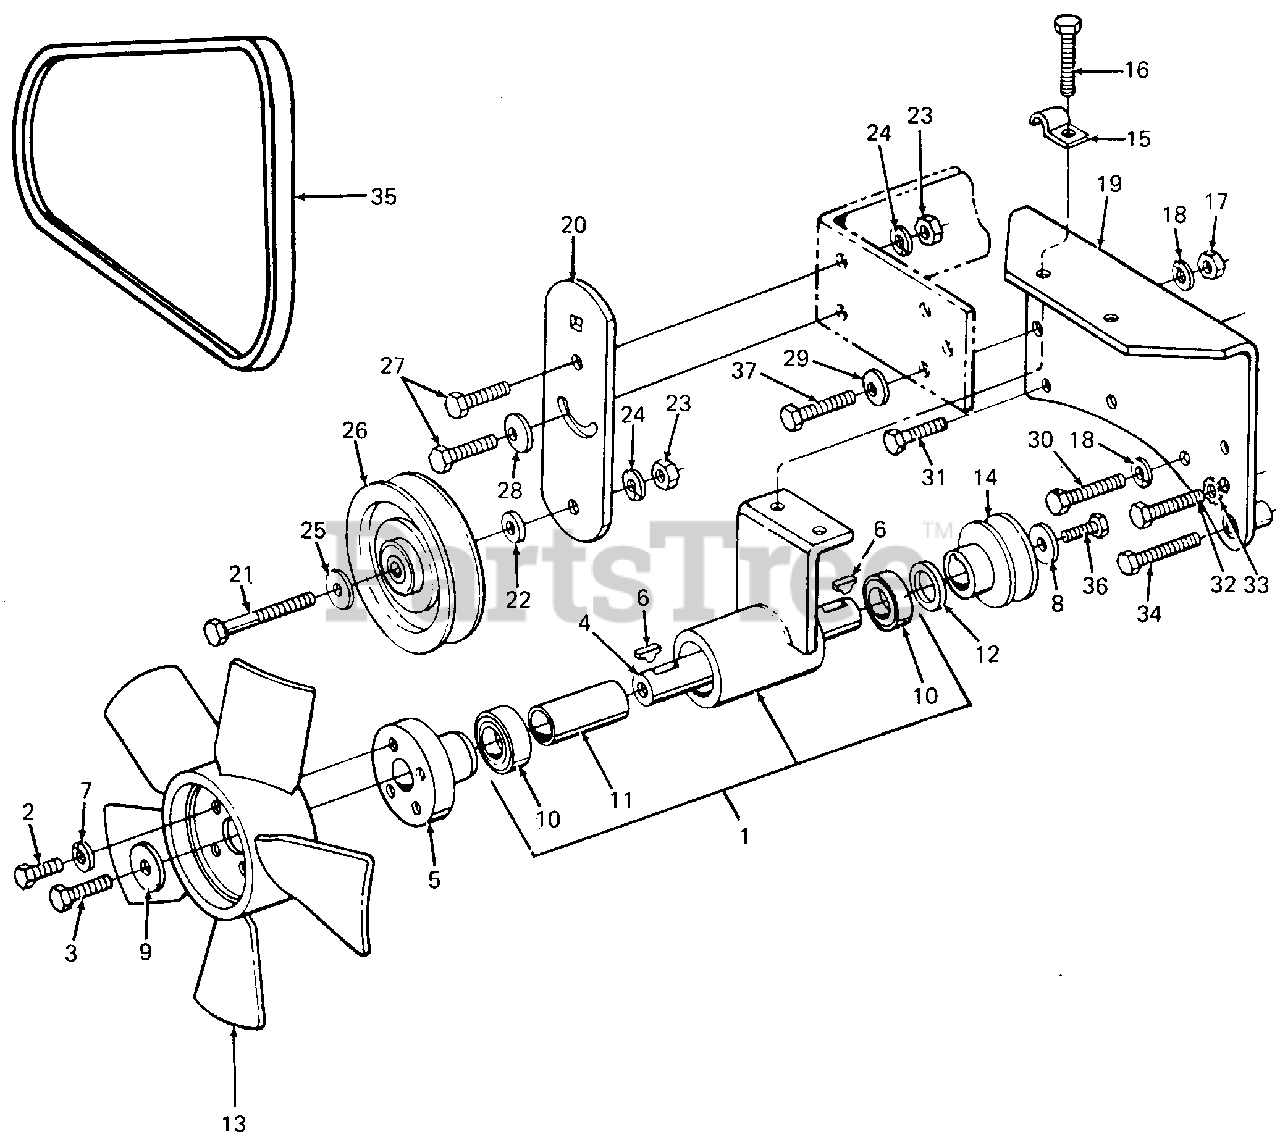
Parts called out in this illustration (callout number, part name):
1	Bracket Assy, Fan
2	Screw, Hex Cap, 1/4-20 X .62 Lg GR5
3	Screw, Hex Patch Lock, 5/16-18 X 1.12 Lg GR5
4	Shaft, Fan
6	Key, #61 HI-PRO, 3/16 X 5/8 Dia
7	Washer, Lock, 1/4
8	Washer, Flat, .344 X 1.12 X .125 Thk HDN
9	Washer, Flat, .344 X 1.0 X .063 Thk HDN
10	Bearing, Ball, .75 X 1.625 X .437
11	Spacer, .755 X 1.0 X 2.110 Lg
12	Spacer, .755 X .94 X .150 Lg
14	Pulley, Engine, 2.38 OD
15	Clip, Cable
16	Screw, Hex Patch Lock, 5/16-18 X .88 Lg GR5
17	Nut, Hex, 5/16-24 GR5
18	Washer, Lock, 5/16
19	Bracket, Fan Mounting
20	Bracket, Idler
21	Screw, Hex Cap, 3/8-16 X 1.75 Lg GR5
22	Spacer, .385 X .625 X .312 Lg
23	Nut, Hex Center Lock, 3/8-16 GR5
24	Washer, Lock, 3/8
25	Washer, Flat, .385 X .62 X .063 Thk
26	Pulley, V-Idler, 3.06 OD
27	Screw, Hex Cap, 3/8-16 X 1.0 Lg GR5
28	Washer, Bell
29	Washer, Bell
30	Screw, Hex Cap, M8-1.25 X 40 mm Lg GR5
31	Screw, Hex Cap, 5/16-24 X 2.0 Lg GR5
32	Screw, Hex Cap, 5/16-18 X 1.25 Lg
33	Washer, Int-Ext Tooth Lock, 5/16 Dia
34	Screw, Hex Cap, 5/16-24 X 1.50 Lg GR5
35	V-Belt, Fan
36	Screw, Hex Patch Lock, 5/16-18 X 1.25 Lg GR5
37	Screw, Hex Cap, 5/16-24 X 1.0 Lg GR5
